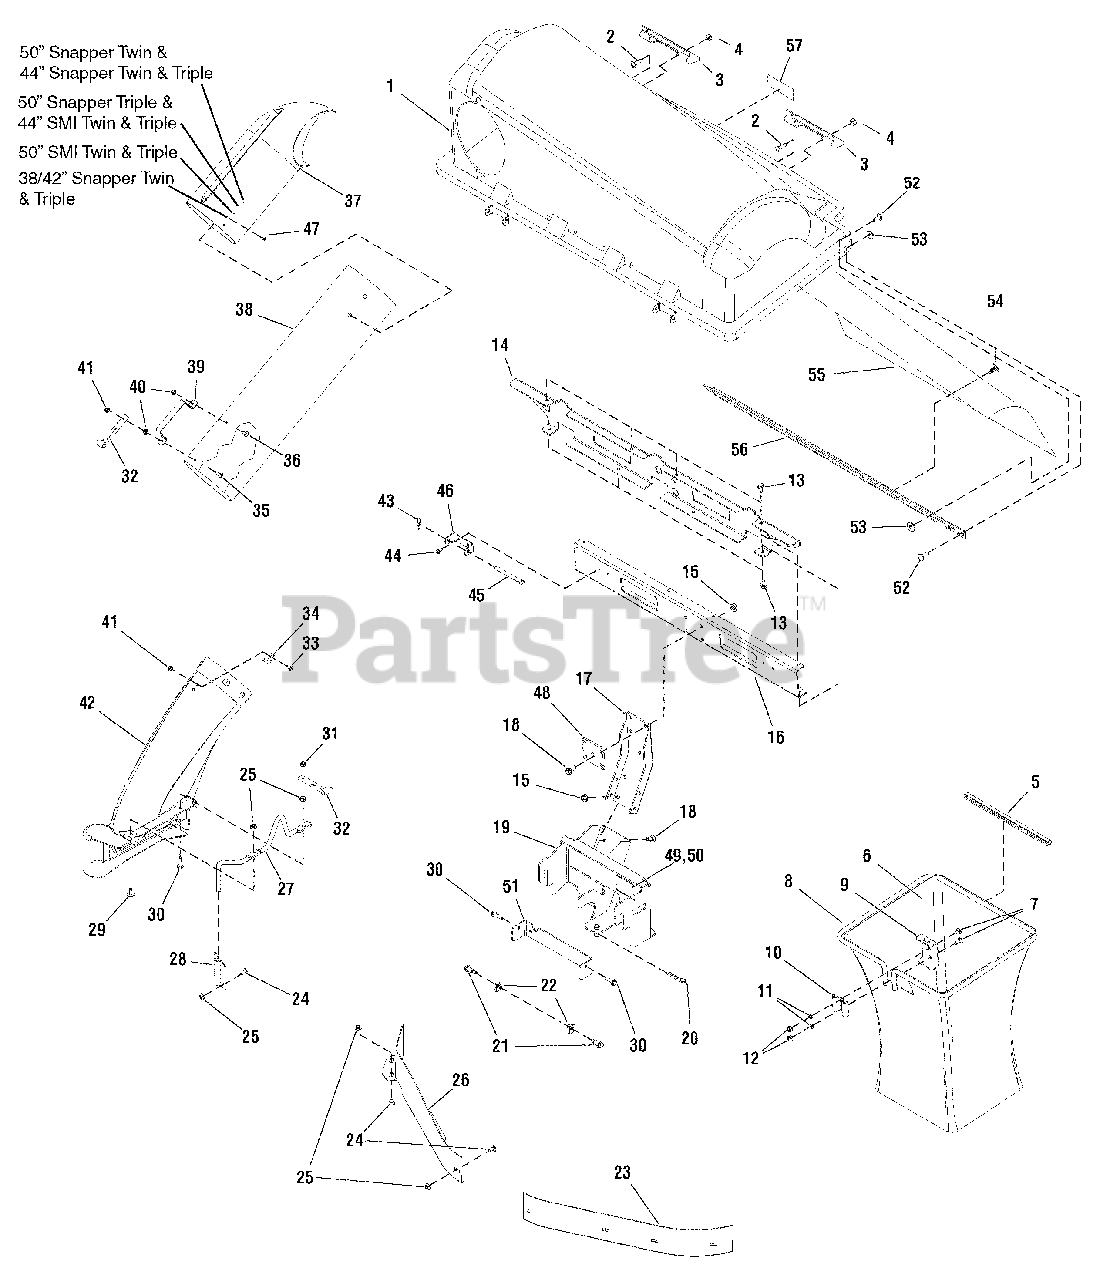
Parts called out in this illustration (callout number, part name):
1	COVER ASSEMBLY, Triple Catcher
2	SCREW, Truss Head Phillips, 10 - 24 x 3/4
3	HANDLE, Plastic
4	NUT, Hex Lock, 10-24 w/Nylon Insert
5	CLIP, Tube Grass Bag
6	BAG, Triple Regular
7	BOLT, Carriage, 5/16 - 18 x 3/4, G5
8	HOOP, Triple
9	HANGER, Grass Bag
10	CLAMP, Grass Bag Plain
11	LOCKWASHER, Spring, 5/16
12	NUT, Hex, 5/16 - 18
13	SCREW, Hex Washer Head Taptite, 5/16 - 18 x 3/4
14	BRACKET, Tab Cross Support Triple
15	NUT, Hex Whiz Lock Flange, 3/8 - 16
16	CHANNEL, Cross Support Triple
17	SUPPORT, Upright
18	SCREW, Hex Whiz Lock Flange, 3/8 - 16 x 1
19	SUPPORT ASSEMBLY
20	CLIP, Hair Pin, 1/8 DIA
21	BOLT, Shoulder, 5/16 - 18
22	NUT, Speed, 5/16 - 18
23	BAFFLE, Blowout L.H. 50" Mower Deck
23	BAFFLE, Blowout L.H. 44" Mower Deck
24	BOLT, Carriage, 5/16 - 18 x 5/8
25	NUT, Hex Whiz Lock Flange, 5/16 - 18
26	BAFFLE, Blowout R.H. 50" Mower Deck
26	BAFFLE, Blowout R.H. 44" Mower Deck
27	ROD, Boot Mount, Deflector Prop, 44/50"
28	PLATE, Chute Rod
29	SCREW, Hex Head, 5/16 - 18 x 3/4
30	SCREW, Hex Whiz Lock Flange, 5/16 - 18 x 1-1/4
31	NUT, Hex Flange Two-Way Lock, 5/16 - 18
32	STRAP, Hood
33	BOLT, Carriage, 1/4 - 20 x 5/8
34	PIN, Latch
35	SCREW, 1/4 - 20 x 1
36	SCREW, 1/4 - 20 x 1/2
37	ELBOW, Upper Tube Poly
38	TUBE, Clear Poly
39	HANDLE, Connect Tube
40	NUT, Hex Keps, 1/4 - 20
41	NUT, Hex Flange Top-Lock, 1/4 - 20
42	TUBE, Boot Poly
43	CLIP, Hair Pin
44	SCREW, Hex Washer Head Taptite, 1/4 - 20 x 1/2
45	PIN, Cover Hinge
46	PIVOT, Hinge
47	SCREW, 1/4 x 3/4
48	PLATE, Reinforcement, Upright
49	STICKER, Serial w/Bar Code
50	MYLAR OVERLAY
51	PLATE, Reinforcement Frame
53	WASHER, Rivet
54	FASTENER, Panel
55	SCREEN, 19-3/4 x 38
56	SUPPORT, Screen
57	DECAL, Warning Thrown Objects
